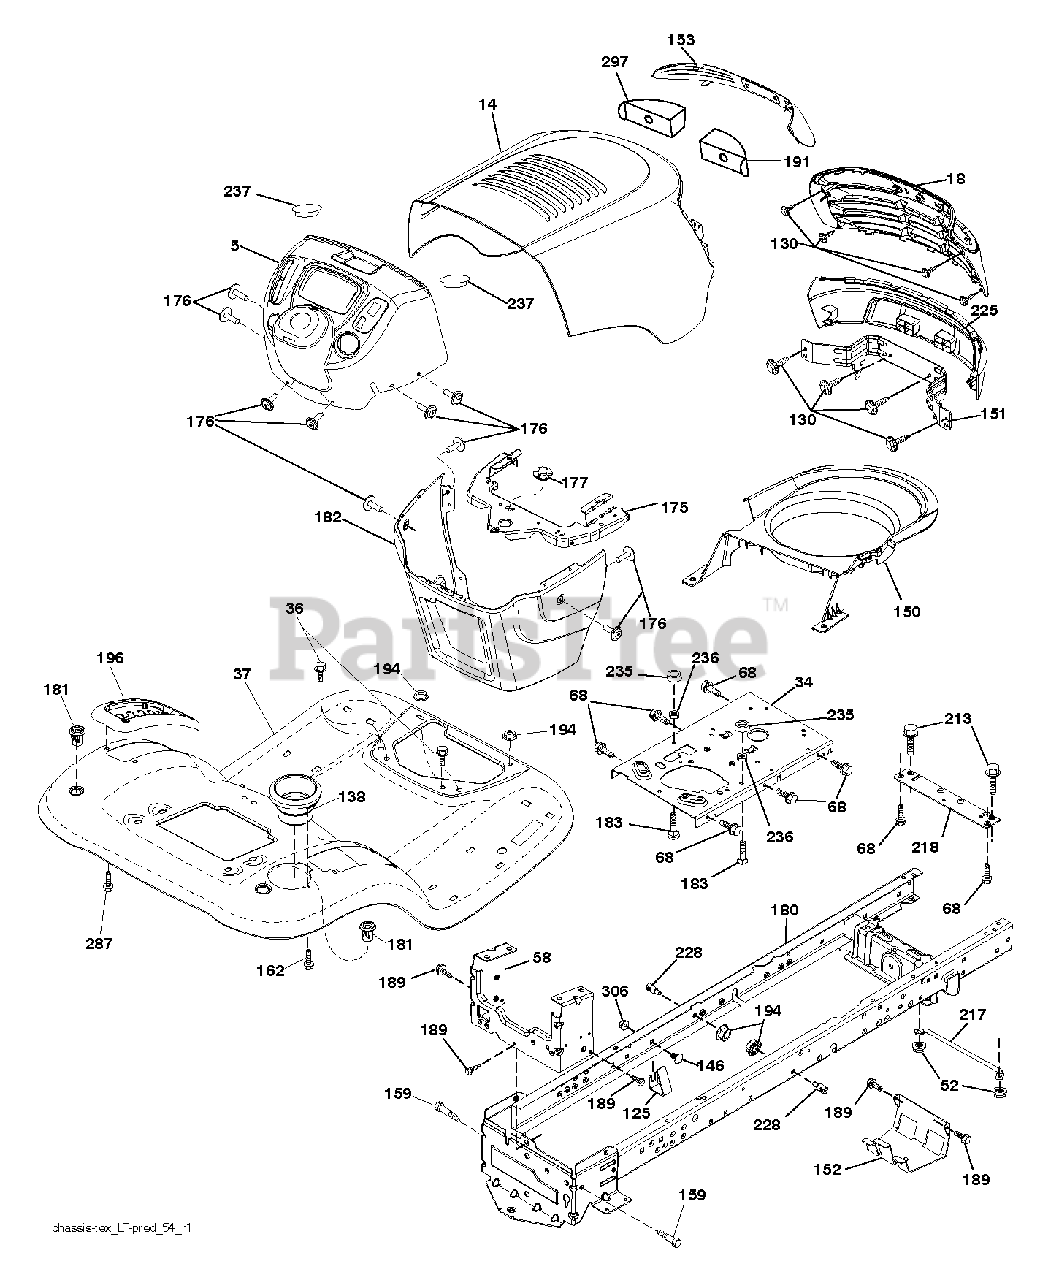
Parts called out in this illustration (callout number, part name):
5	DASH.PRED.LT.CC.ICY.N/SRV.BLK
14	HOOD.PREDATR.LT.BLUE.DIXON
18	GRILLE SVC.PPRED.LT.DIXON.BLCK
34	PLATE.ENGINE.WELDED.CHASSIS
36	SCREW 5/16"
37	FENDER.TLT.FS.W/CUPHLD.666
52	LOCKNUT
58	DRAWBAR UPPER 2PC SMALL FENDER
68	SCREW LT
125	CLIP.FUEL.LINE
130	SCREW.#10 X 0.750.BOS (2 2)
138	CUPHOLDER.TL.TEX.BLACK
146	BOLT.RDHD.SHT.SQNK.3/8-16X5/8
150	DUCT.AIR.TOP.VENT.PREDATOR.LT
151	BRACKET.PIVOT.ALPHA.LT
152	SHIELD.BROWNING.W/TEX
153	LENS.PREDATOR.LT
159	SCREW, 3/8-16X3/4
162	SCREW.HI-LO.CONSOLE
175	CROSSMEMBER
176	SCREW.#10-24X5/8.RN.QU
177	BUSHING STEERING
180	CHASS.WLDMNT.TL.12GA/2P.48/54
181	FEND/FTRST.PCH.CPH.NFW
182	DASH.LOWER.PREDATOR LT
183	BOLT.5/16-18X1-1/4 FULL.THREAD
189	SCREW
191	INSERT.REFLECT.PREDATOR.LT.RH
194	NUT LOCK HEX FLANGE 5/16-18
196	CONSOLE.ASM.DECKLFT.BL/RBT.TLT
213	BOLT
217	ROD.PIVOT.HOOD
218	X-PIECE.HOOD.STOP.NON/
225	BUMPER.PREDATOR.LT.BLUE.DIXON
228	STUD.FASTNER.W/ANTI-ROTATE
235	SPACER FENDER
236	NUT.CENTERLOCK.5/16-
237	PLUG.MOUNT.CARGO.BLK
287	SCREW 1/4X20
297	REFLECTOR.INSERT.PRED.LH.LT
306	NUT LOCK FLG 3/8-16 UNC
